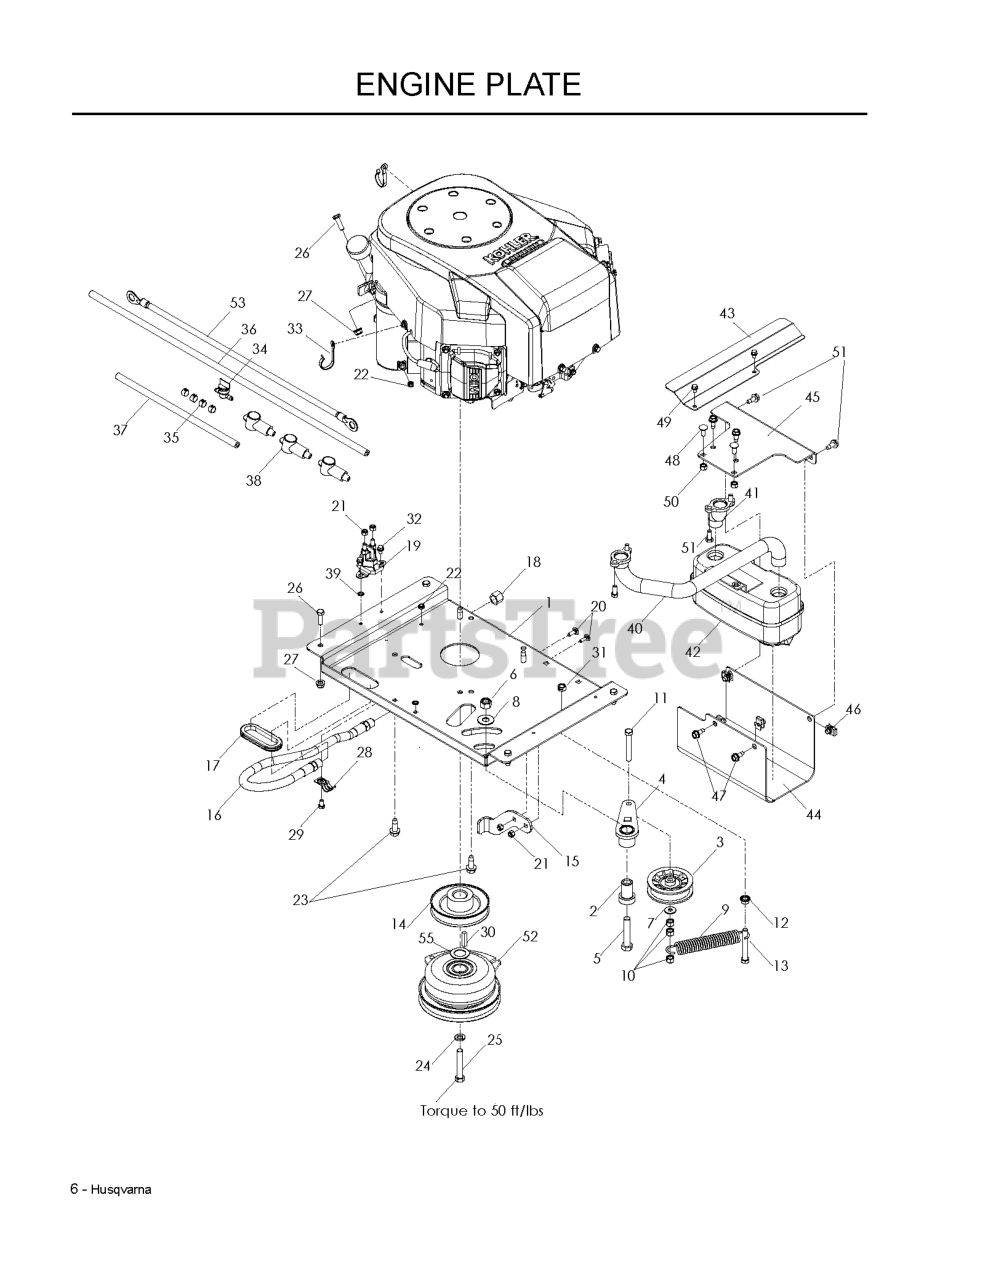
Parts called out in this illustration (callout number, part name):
1	PLATE, ENGINE
2	IDLER SPINDLE
3	PULLEY, IDLER RAKE & ZTR
4	RP.IDLER ARM WELDMENT
5	HEX SCREW 1/2-13 X 2.5" GR 5
6	NUT 1/2-13 HEX NYLOC ZD
7	WASHER 5/16 FLAT
8	WASHER 1/2 FLAT
10	NUT 3/8-16 NYLOC
11	HCS 3/8-16 X 2-1/2 TPBLT
12	NUT 3/8C WHIZ
13	SCREW 3/8C X 2 3/4 HEX CAP
15	TIE DOWN, CLUTCH
16	DRAIN, OIL
20	RHSNB 1/4C X 3/4
21	NUT.1/4-20.HEX.NYLOC.ZD
22	JAM NUT 1/4C (2 2 PW01)
23	HHFS 3/8-16 X 1.0 THD FORMING
24	WASHER 7/16 LOCK
25	BOLT 7/16F X 2 1/2
26	HCS 5/16C X 1
27	5/16-18 NYLOC FLANGE NUT
29	HCS 1/4-20.
30	KEY, 1/4 SQ X 1 1/4
31	NUT 3/8C CENTERBLOCK
32	HWST 1/4C X 3/8
34	FUEL VALVE
35	HOSE CLAMP
36	FUEL LINE 30"
37	FUEL LINE 13"
39	WASHER 1/4 INT TOOTH
40	MANIFOLD, FT
41	MANIFOLD, RR
42	MUFFLER ASM TWIN
43	SHIELD, HEAT
44	GUARD, MUFFLER
45	MOUNT MUFFLER BLACK
46	U-CLIP 5/16-18 NUT RETAINER
47	BOLT 5/16-18 X 3/4
48	BOLT 5/16C X 3/4" CARRIAGE
49	HWST 1/4C X 3/8
50	NUT 5/16 NYLOC
51	HCS 5/16C X 3/4
52	CLUTCH, 200 FT/LB
53	CABLE, POSITIVE
55	WASHER, 1.025 ID X 1.64
